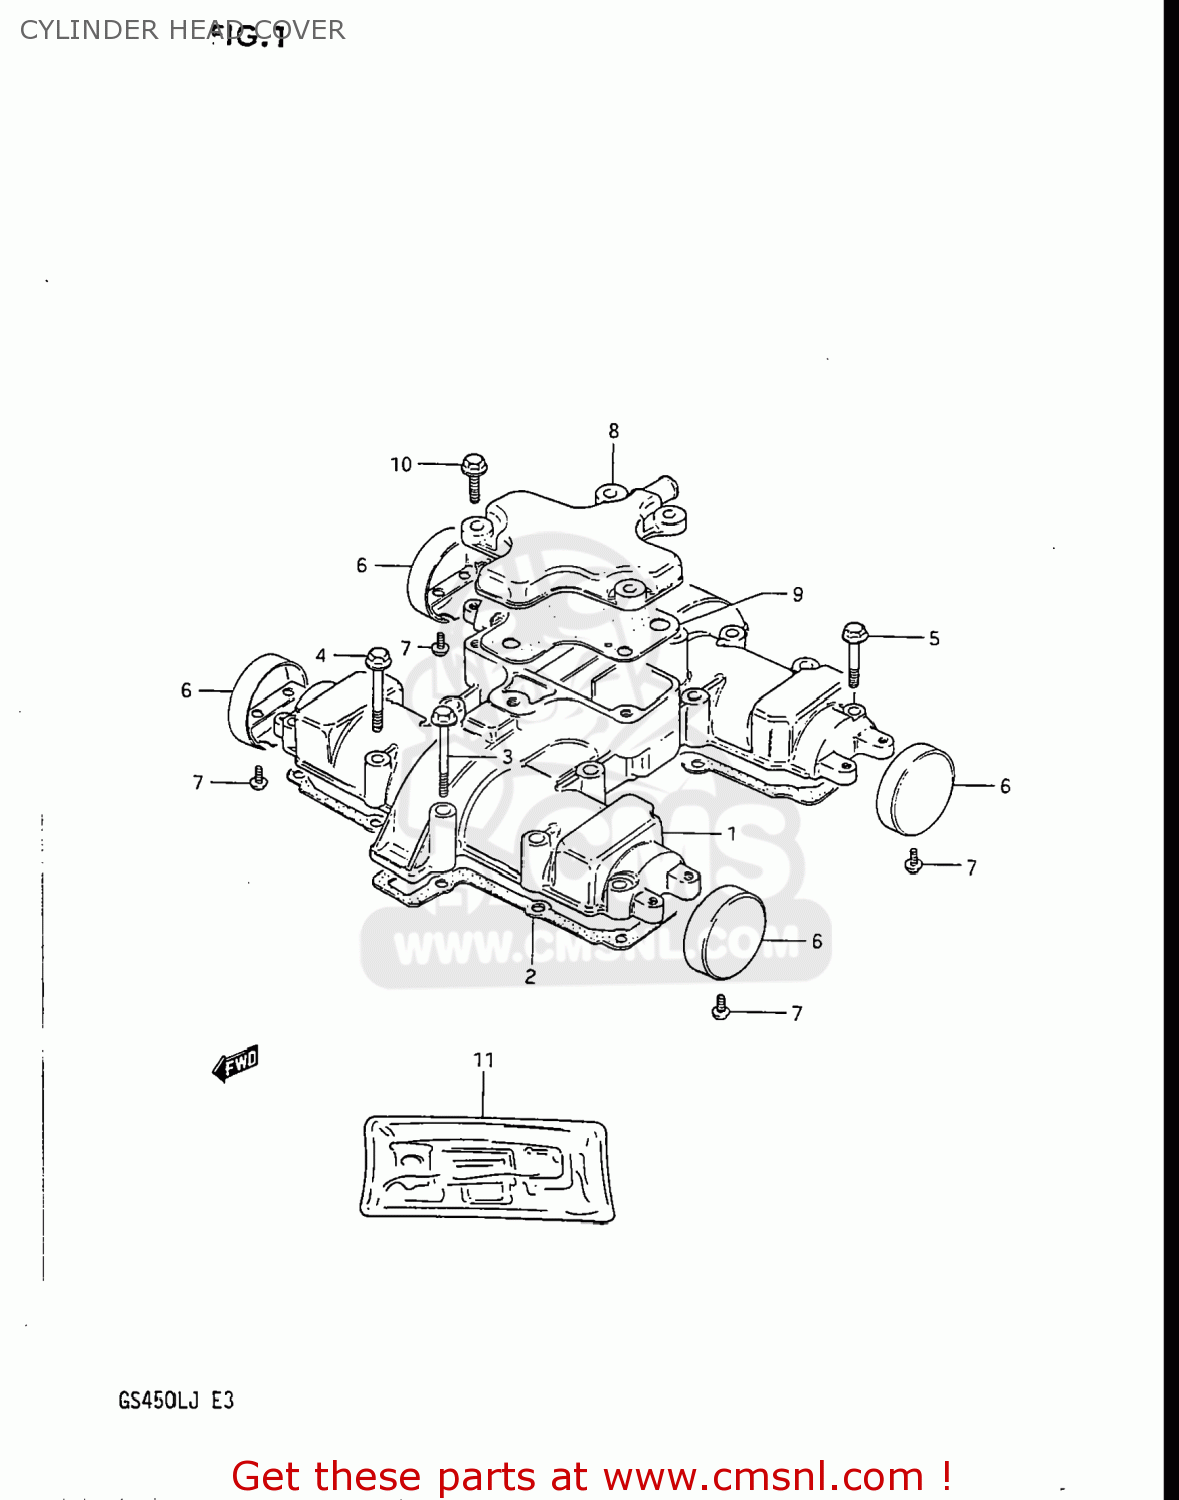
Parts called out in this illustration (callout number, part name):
1	COVER,CYLINDER HEAD
2	GASKET,CYLINDER HEAD COVER (MCA)
3	BOLT (6X45)
4	BOLT
5	BOLT 6X30
6	CAP,CYLINDER HEAD COVER
7	SCREW
8	COVER,BREATHER
9	GASKET (MCA)
10	BOLT
11	GASKET SET
